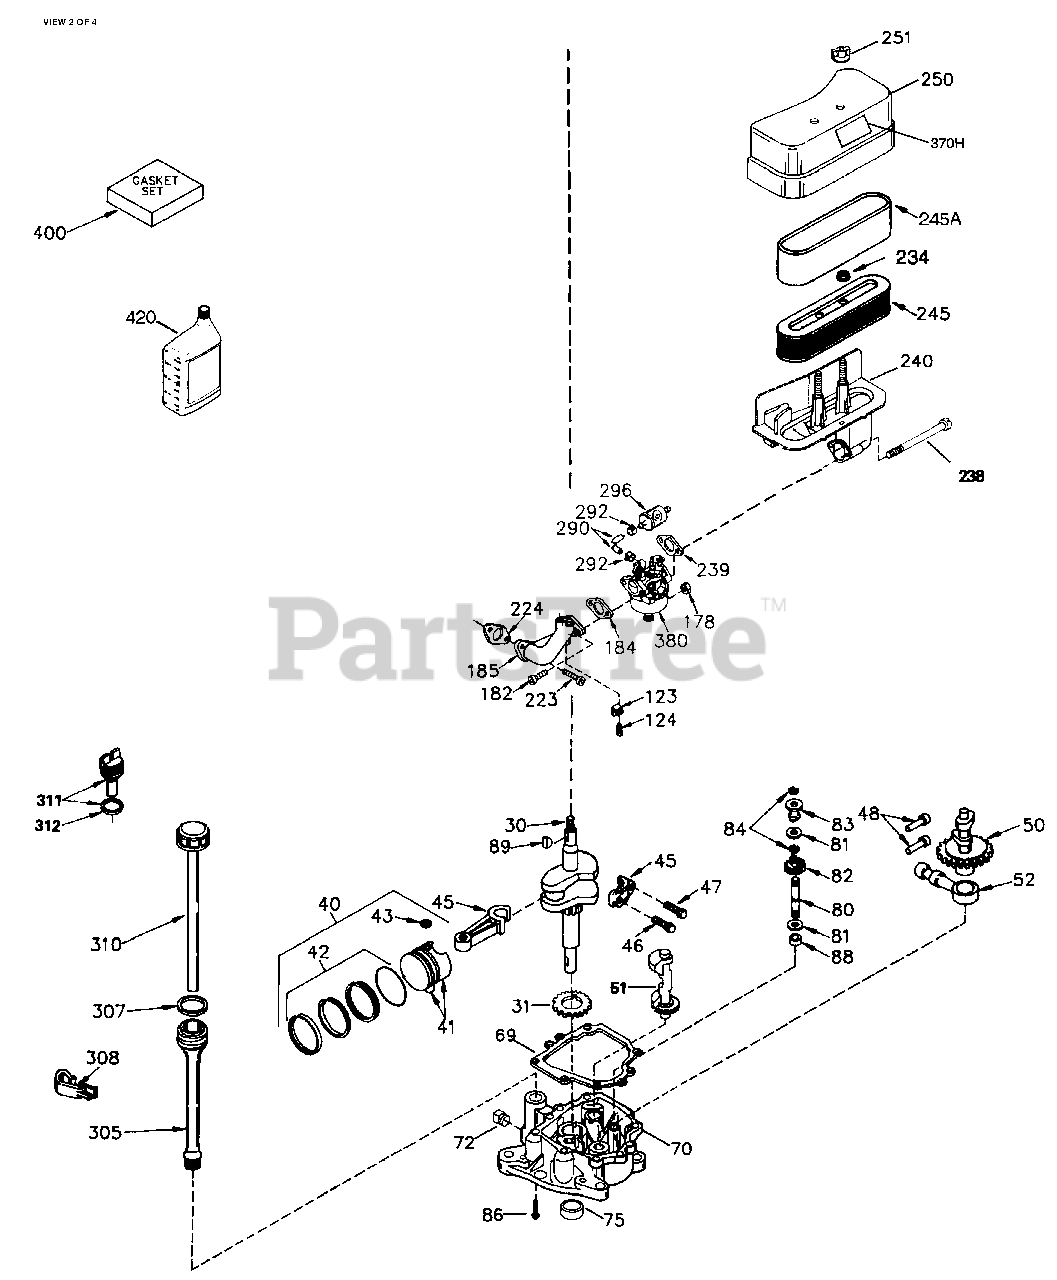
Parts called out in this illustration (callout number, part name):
30	Crankshaft
31	Counterbalance Gear
40	Piston, Pin & Ring Set (.020" OS) (In cl. 41, 42 & 43)
40	Piston, Pin & Ring Set (Std) (Incl. 4 1, 42 & 43)
40	Piston, Pin & Ring Set (.010" OS) (In cl. 41, 42 & 43)
41	Piston & Pin Assembly (Std) (Incl. 43 )
41	Piston & Pin Ass'y. (.010" OS) (Incl. 43)
41	Piston & Pin Ass'y. (.020" OS) (Incl. 43)
42	Ring Set (Std.) (3-5/16")
42	Ring Set (.010" OS)
42	Ring Set (.020" OS)
43	Piston Pin Retaining Ring
45	Connecting Rod Ass'y. (Incl. 47)
47	Connecting Rod Bolt
48	Valve Lifter
50	Camshaft (MCR)
51	Counterbalance Weight
52	Oil Pump Ass'y.
69	Mounting Flange Gasket
70	Mounting Flange (Incl. 72, 75 & 80)
72	Oil Drain Plug
72A	Oil Drain Plug
75	Oil Seal
80	Governor Shaft
81	WASHER
82	Governor Gear Assembly
83	Governor Spool
84	Retaining Ring
86	Screw, 1/4-20 x 1-3/16"
88	Spacer (Incl. 81)
159	Rocker Arm Cover Gasket
184	Intake To Head Gasket
224	Intake To Cylinder Gasket
239	Carburetor Gasket
306	Oil Fill Tube Gasket
361A	Screw, 1/4-20 x 1-13/32"
